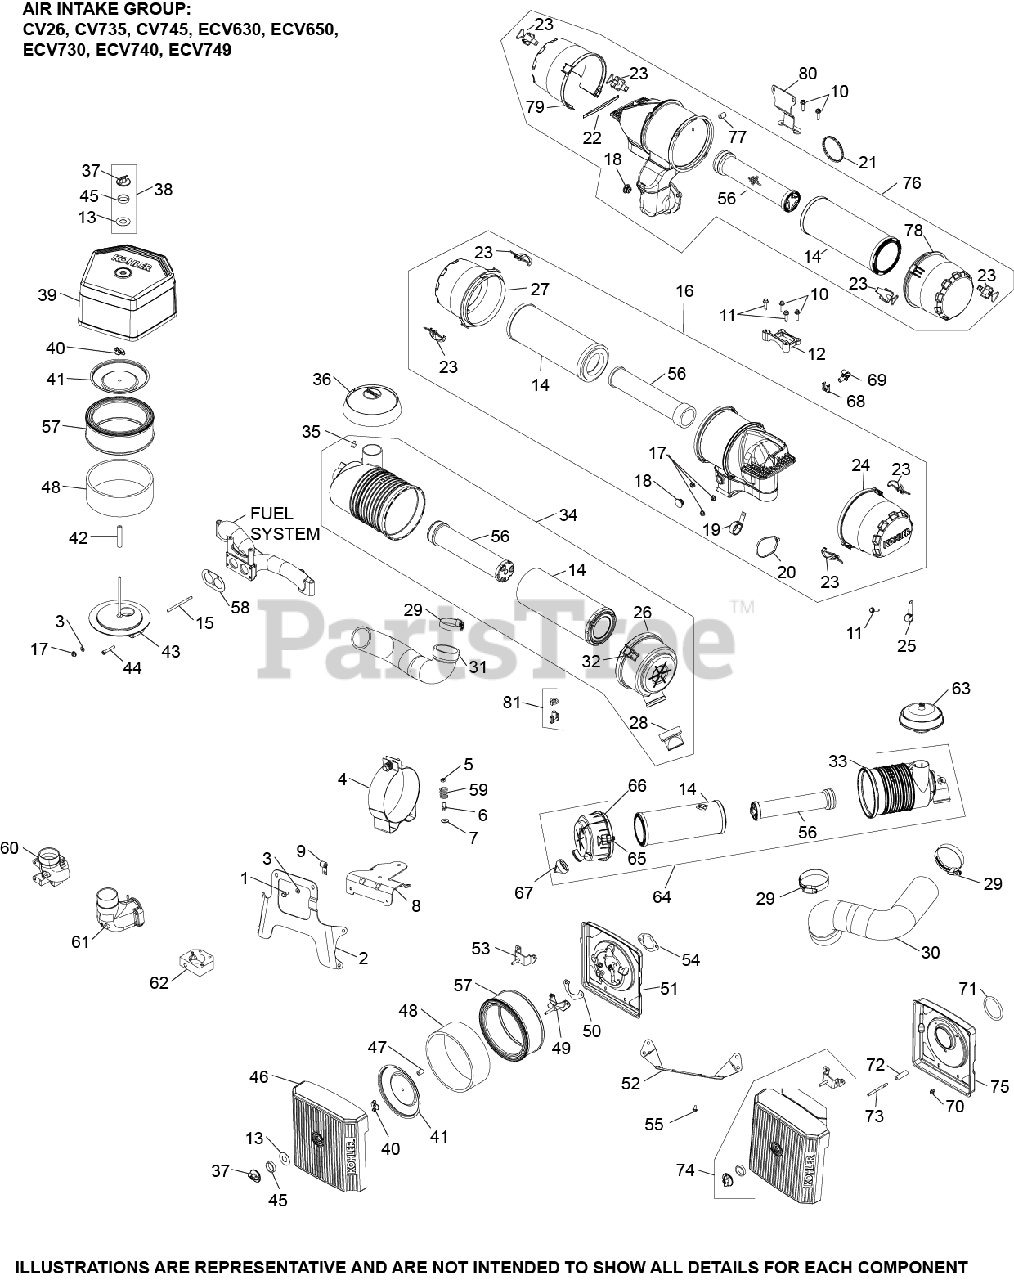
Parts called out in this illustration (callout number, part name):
11	SCREW, THREAD FORMING
12	BRACKET, A/C VERT HDAC (EFI)
14	ELEMENT, AIR FILTER - PRIMARY
16	FILTER, AIR ASSEMBLY
18	PLUG, HOLE
21	O-RING (HDAC SEAL-EFI)
22	DAMPER, FOAM INSERT
23	CLIP ASSEMBLY
24	COVER, RAIN CAP
25	CLIP, CABLE
27	COVER, AIR FILTER
56	ELEMENT, AIR FILTER - SAFETY
